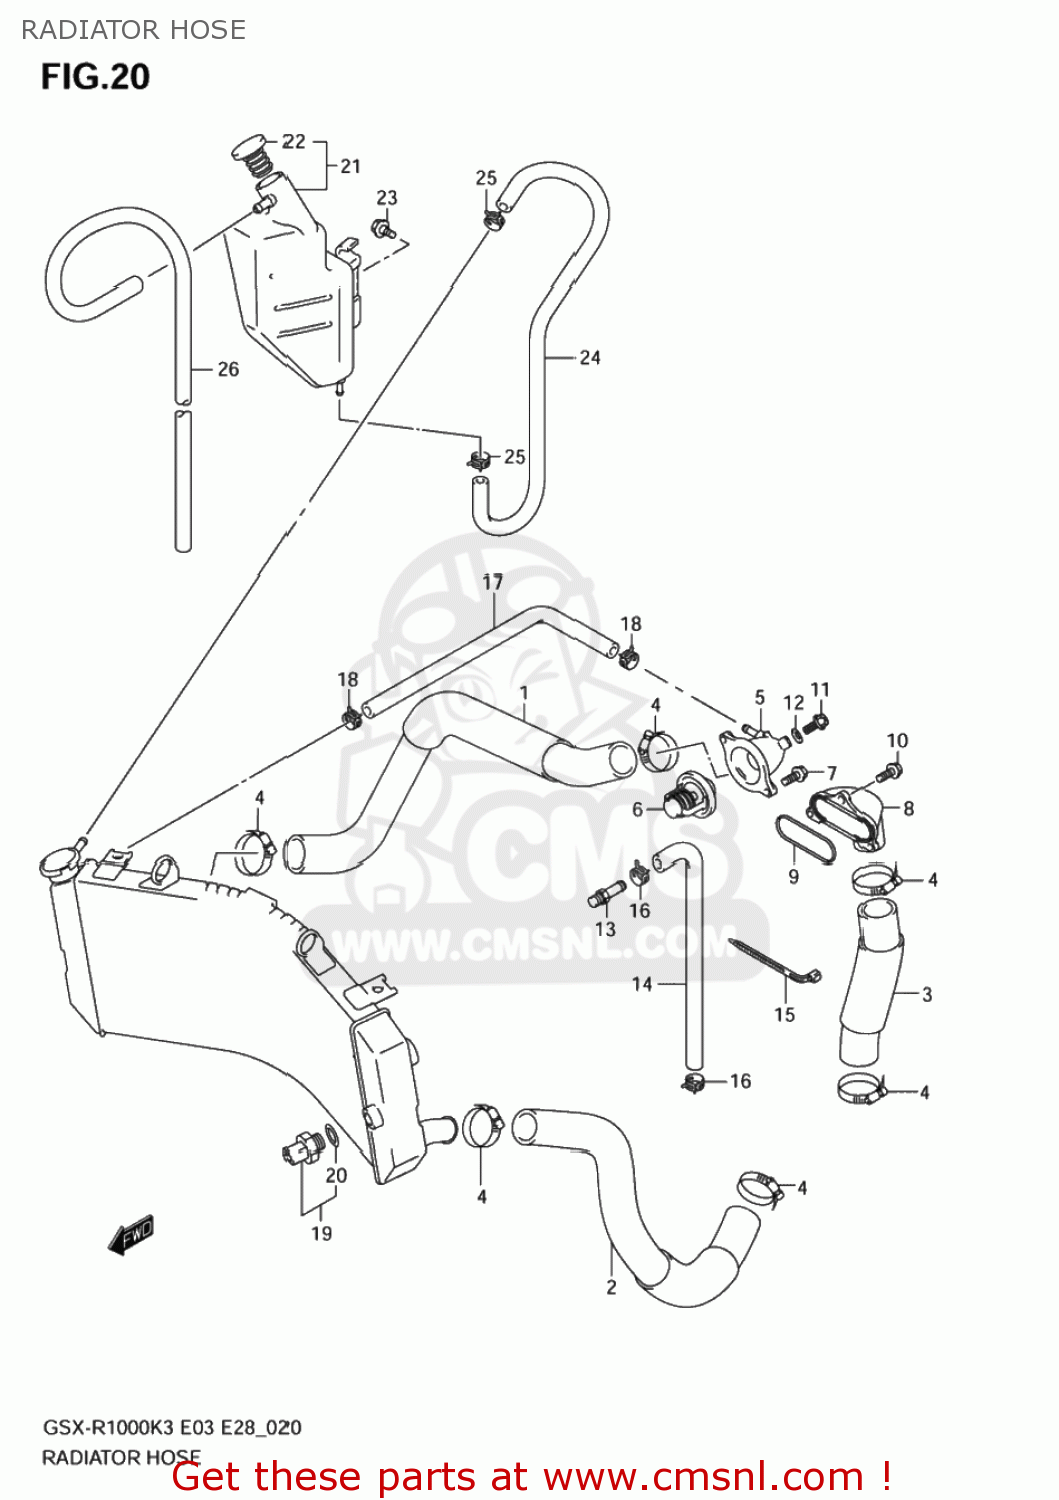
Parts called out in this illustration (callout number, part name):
1	HOSE,RADIATOR INLET
2	HOSE,RADIATOR OUTLET
3	HOSE,CYLINDER INLET
4	CLAMP
5	COVER,THERMOSTAT
6	THERMOSTAT,WATER
7	SCREW
8	CONNECTOR,CYL.
9	O RING,CYL WATER CONNECTOR
10	SCREW
11	UNION BOLT,AIR VENT
12	GASKET(6.4X11.5X0.8) (NAS)
13	BOLT UNION
14	HOSE,WATER BYPASS
15	CLAMP(L:165)
16	CLAMP
17	HOSE(5X11X600)
18	CLIP
19	SWITCH,RADIATOR FAN
20	O-RING
21	TANK ASSY,RESERVOIR
22	CAP,RESERVOIR TANK
23	BOLT(6X12)
24	HOSE,RESERVOIR TANK INLET
25	CLIP
26	HOSE,RESERVOIR
